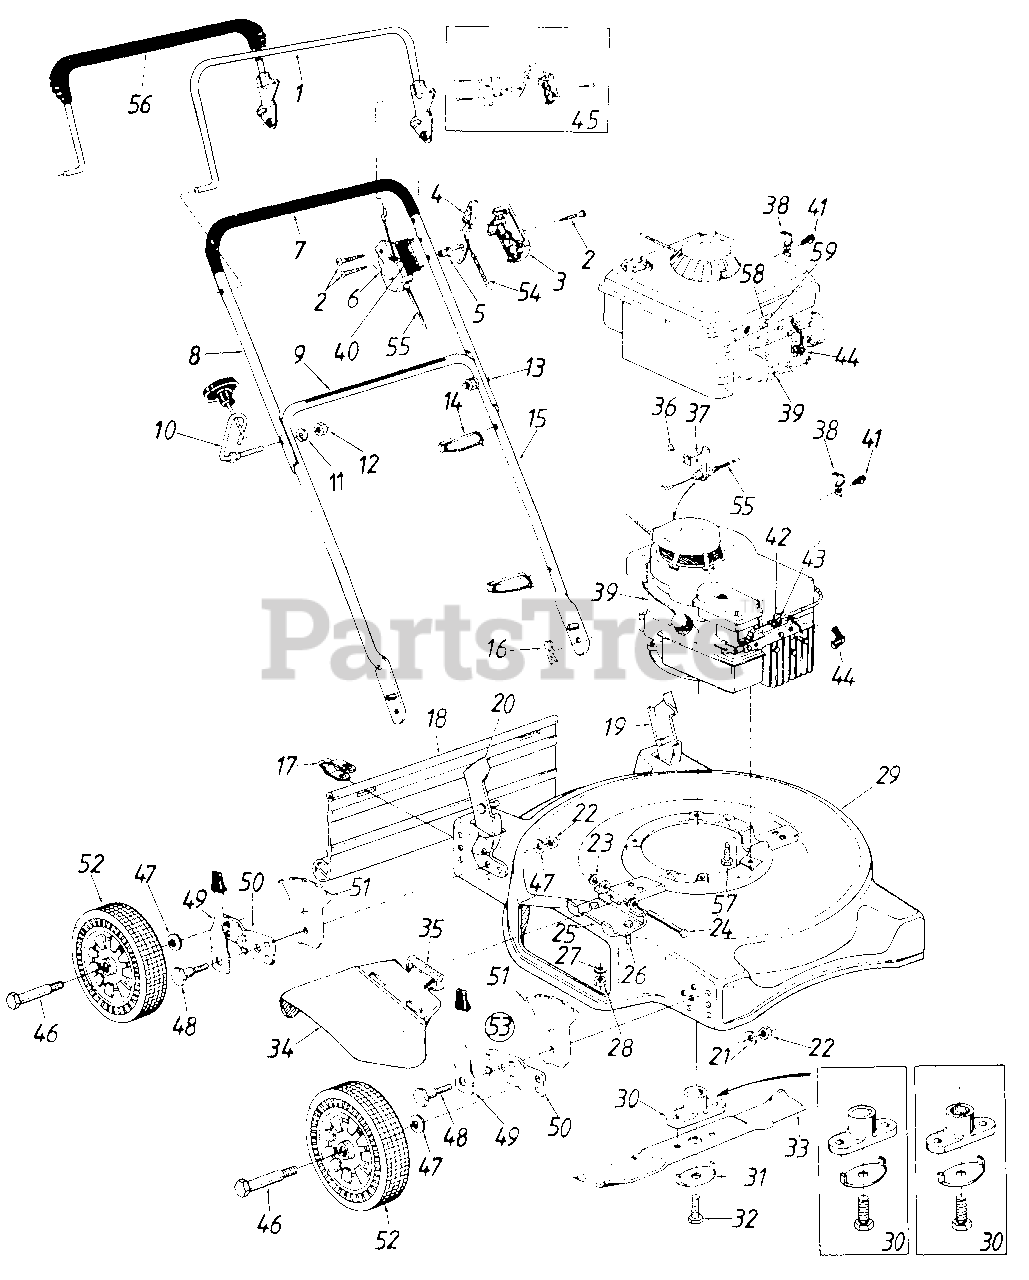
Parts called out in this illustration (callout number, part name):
1	Control Handle Ass'y.
2	Truss Mach. Scr. #12 x 1.5" Lg.
3	Control Panel Half
4	Throttle Control Lever
5	Control Disc Pin
6	Clutch Panel Half
8	Upper Handle
9	Instruction Label-Handle
10	Rope Guide Bolt
11	L-Wash. 5/16" I.D.
12	Hex Nut 5/16-18 Thd.
13	Curved Carriage Bolt 5/16-18 x 1.38" Lg.
14	Cable Tie
15	Lower Handle
16	Hairpin Cotter
17	Hinge Clip
18	Rear Flap
19	Handle Bracket Ass'y.-L.H.
20	Handle Bracket Ass'y.-R.H.
21	Bell-Wash. .39" I.D. x 1.38"
22	Hex Nut 3/8-16 Thd.
23	Push Cap 1/4" Rod
24	Pivot Pin
25	Adapter Plate
26	Hex Bolt 1/4-20 x .50" Lg.*
27	L-Wash. 1/4" I.D.
28	Hex Nut 1/4-20 Thd.
30	Blade Adapter Kit Keyed)
31	Blade Bell-Wash. .45" I.D. x 2.38"
32	Hex Bolt 3/8-24 x 1.5" Lg.
33	20" Blade
34	Chute Deflector Ass'y.
35	Torsion Spring
36	Pop Rivet
37	Cable Bracket
38	Cable Clamp
39	Engine
40	Control Label-Throttlet
41	Hex B-Tap Scr. #10 x .38"
42	Cable Clamp
43	Hex AB-Tap Scr. #8 x .38" Lg.
44	Spark Plug Boot
45	Kit-Control Housing Comp.
46	Axle Bolt
47	Bell-Wash. .400" I.D. x .88"
48	Shld. Bolt .50" Dia. x .357"
49	Spring Lever Ass'y. w/Knob
50	Pivot Bar
51	Height Adj. Plate
52	Wheel Ass'y. Comp.
53	Height Adj. Ass'y. Comp.-R.H.
54	Throttle Cable-51"
55	Control Cable-39"
56	Control Handle Ass'y.
57	Hex L-Wash. Hd. Scr. 3/8-16 x 1.0" Lg.
58	Cable Clamp
59	Hex B-Tap Scr. #10 x .62" Lg.
